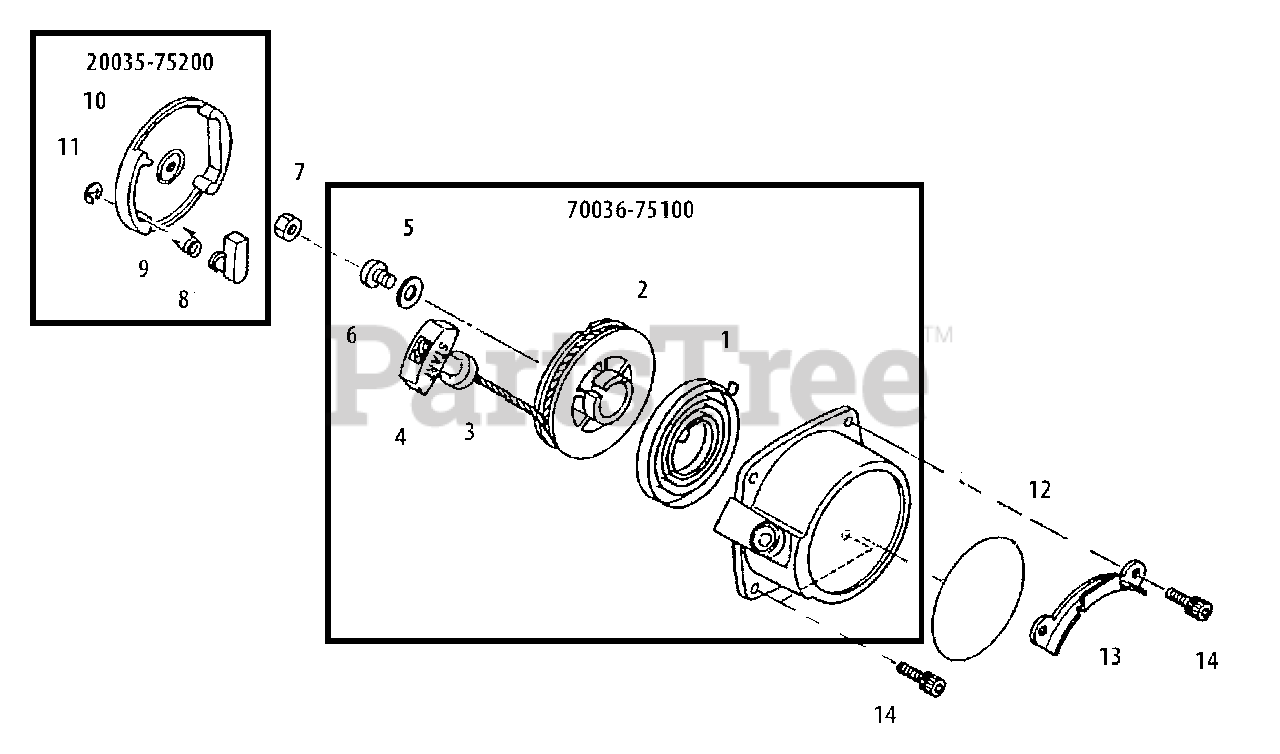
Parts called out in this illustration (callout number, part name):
1	SPRING, REWIND
2	REEL, ROPE
3	ROPE, STARTER
4	GRIP, STARTER
5	WASHER
6	SCREW
7	NUT
8	RATCHET
9	SPRING, RETURN
10	REEL, ROPE
11	RING, RETAINING
12	LABEL - IDENTIFICATION
13	BRACKET
14	SCREW - 4X16
20035-75200	STARTER PAWL ASSY
70036-75100	STARTER ASSY
